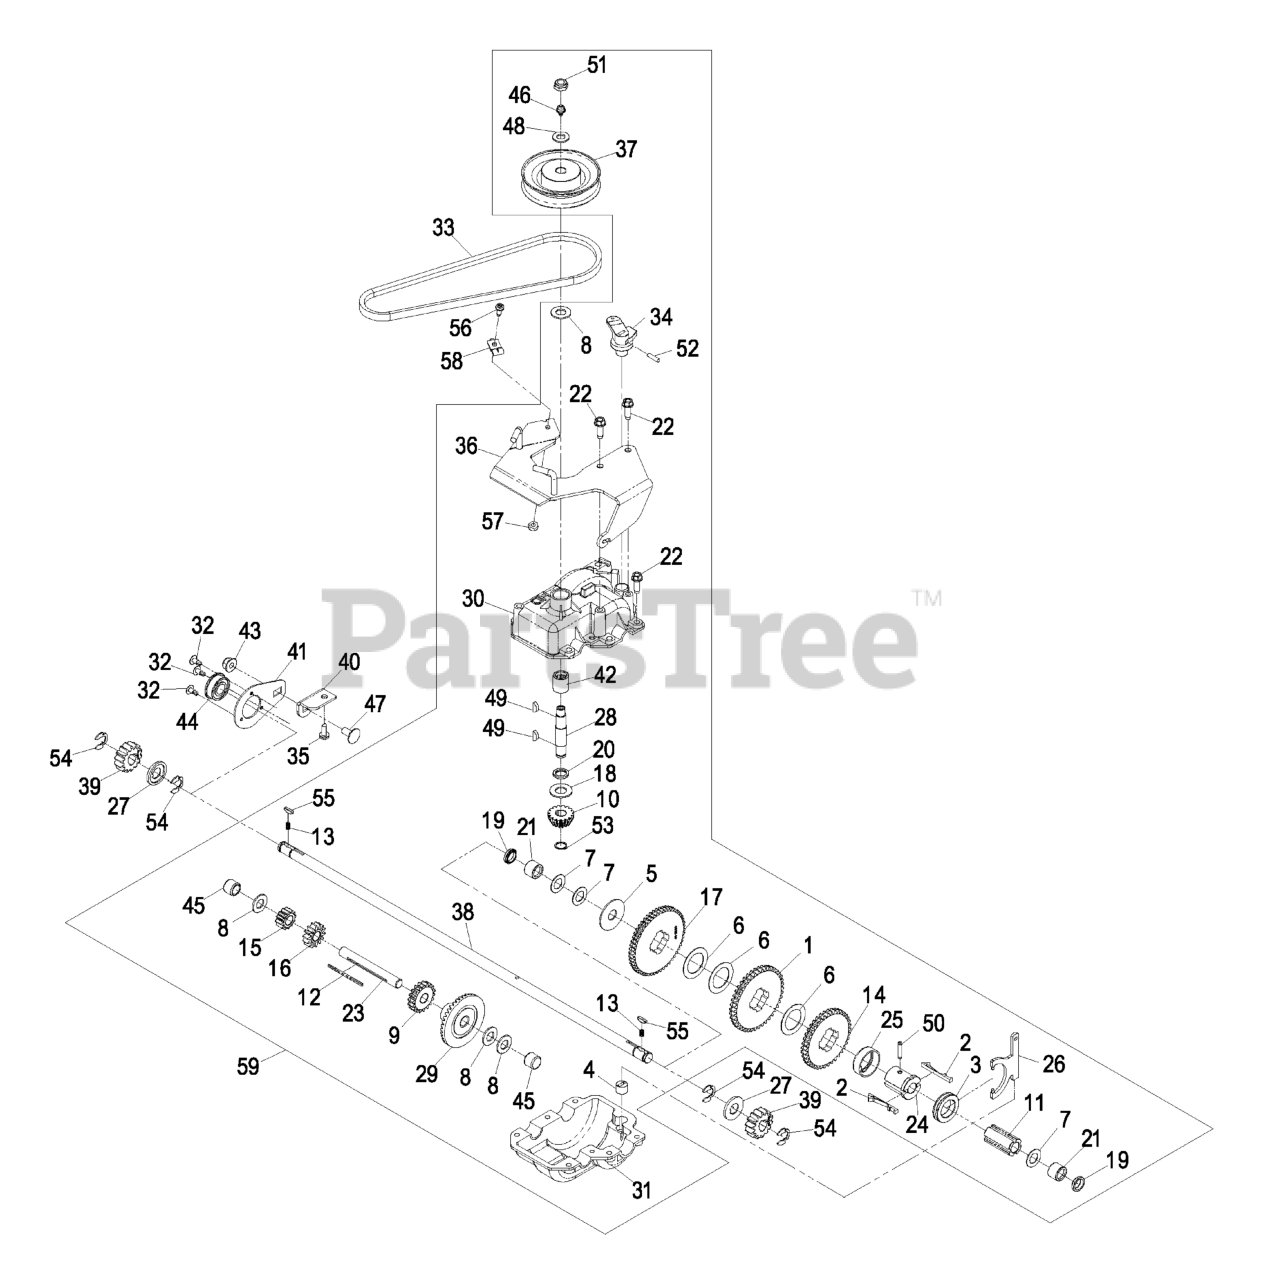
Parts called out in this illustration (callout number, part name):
1	GEAR-42T
2	KEY-SHIFT
3	COLLAR-SHIFT
4	BUSHING-YOKE
7	WASHER-PLAIN
8	WASHER-THRUST
9	GEAR-18T
10	PINION-BEVEL
13	SPRING-COMPRESSION
14	GEAR-38T
15	GEAR-12T
16	GEAR-14T
18	WASHER-THRUST
19	SEAL-OIL
22	SCREW-HWHTF
23	SHAFT-INTERMEDIATE
24	SLEEVE-GEAR
25	RETAINER-KEY
26	YOKE-SHIFT
27	WASHER-THRUST, OUTER
28	INPUT SHAFT ASM
29	GEAR-BEVEL
30	ASM,GEAR CASE W/BRG
32	SCREW-TAP
33	BELT-V, TRACTION
34	LEVER-SHIFT
35	SCREW-TP
38	SHAFT-AXLE
39	GEAR-PINION
42	BEARING-ROLLER, CAGED
43	NUT-HF, NI
45	BEARING-NEEDLE, CLOSED
46	FITTING-GREASE, ZERK
47	SCREW-CARR
48	WASHER-FLAT
49	KEY-WOODRUFF
50	PIN-GROOVE
51	NUT-HEX
52	PIN-SPRING
53	RING-RETAINING
54	RING-RETAINING
56	SCREW-FORMING, THREAD
57	NUT-LOCK, NI
58	CLAMP-CABLE
